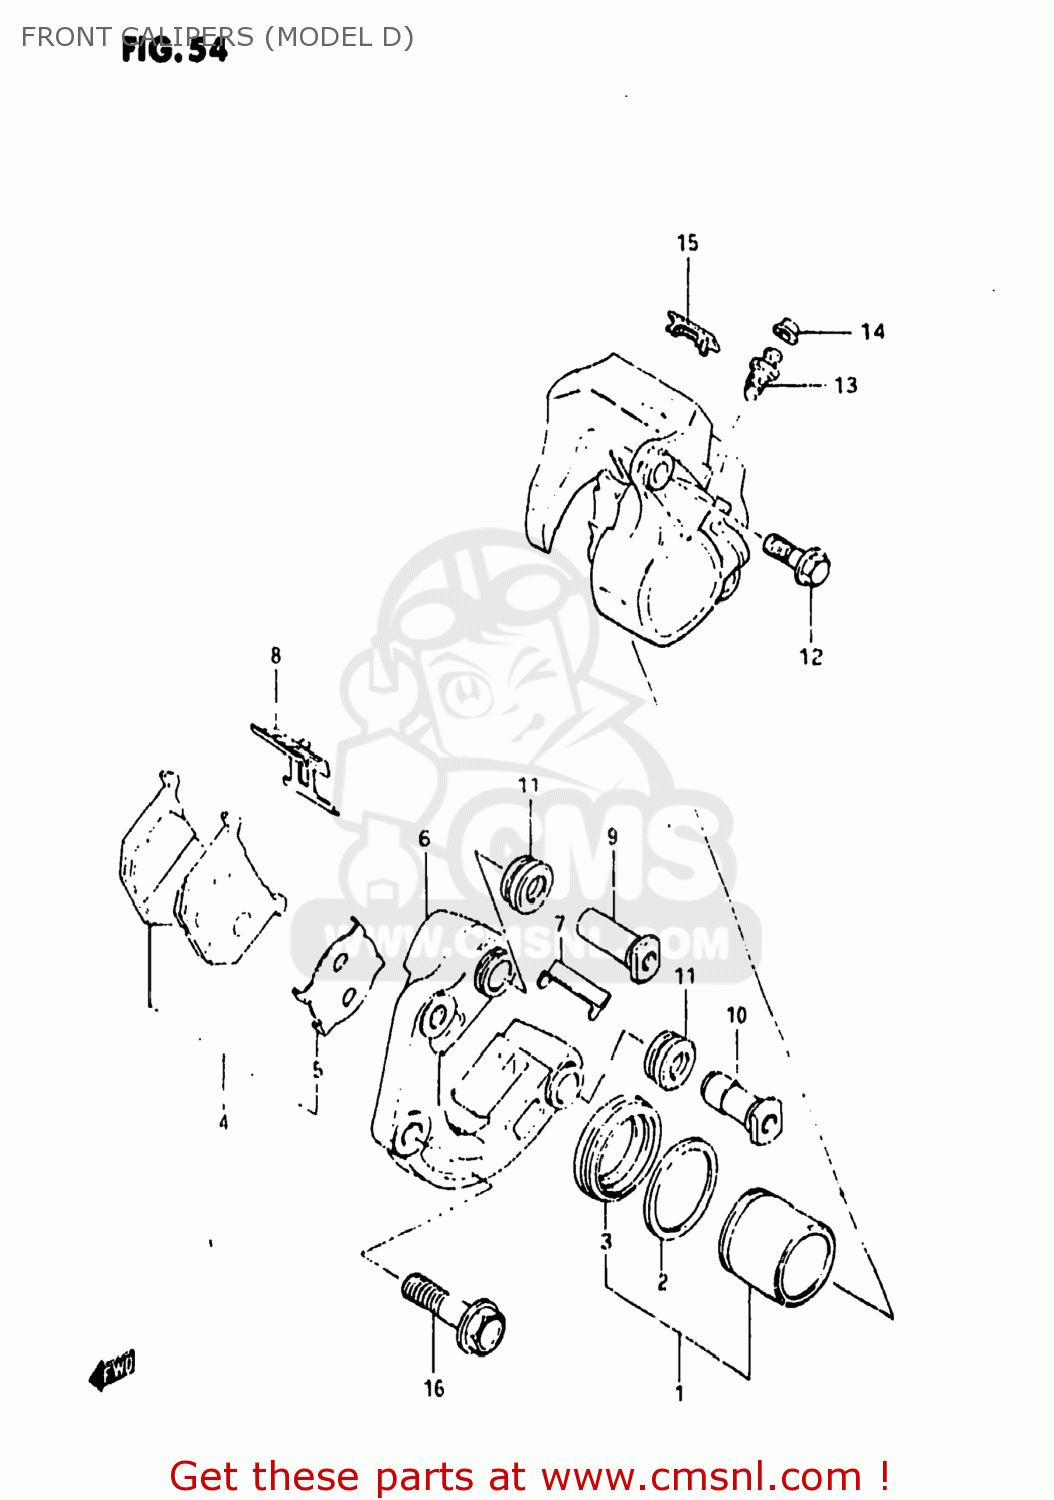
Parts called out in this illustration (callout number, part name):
0	CALIPER ASSEMBLY,FRONT,LEFT
1	PISTON SET
2	SEAL,PISTON
3	BOOT,PISTON
4	PAD SET,BRAKE (MCA)
5	SHIM,PAD
6	CARRIER,CALIPER,LEFT
7	GUIDE,PAD
8	SPRING,PAD
9	AXLE NO.1
10	AXLE NO.2
11	BOOT,AXLE
12	BOLT
13	BLEEDER
14	CAP,BREATHER
15	COVER
16	BOLT(10X37)
